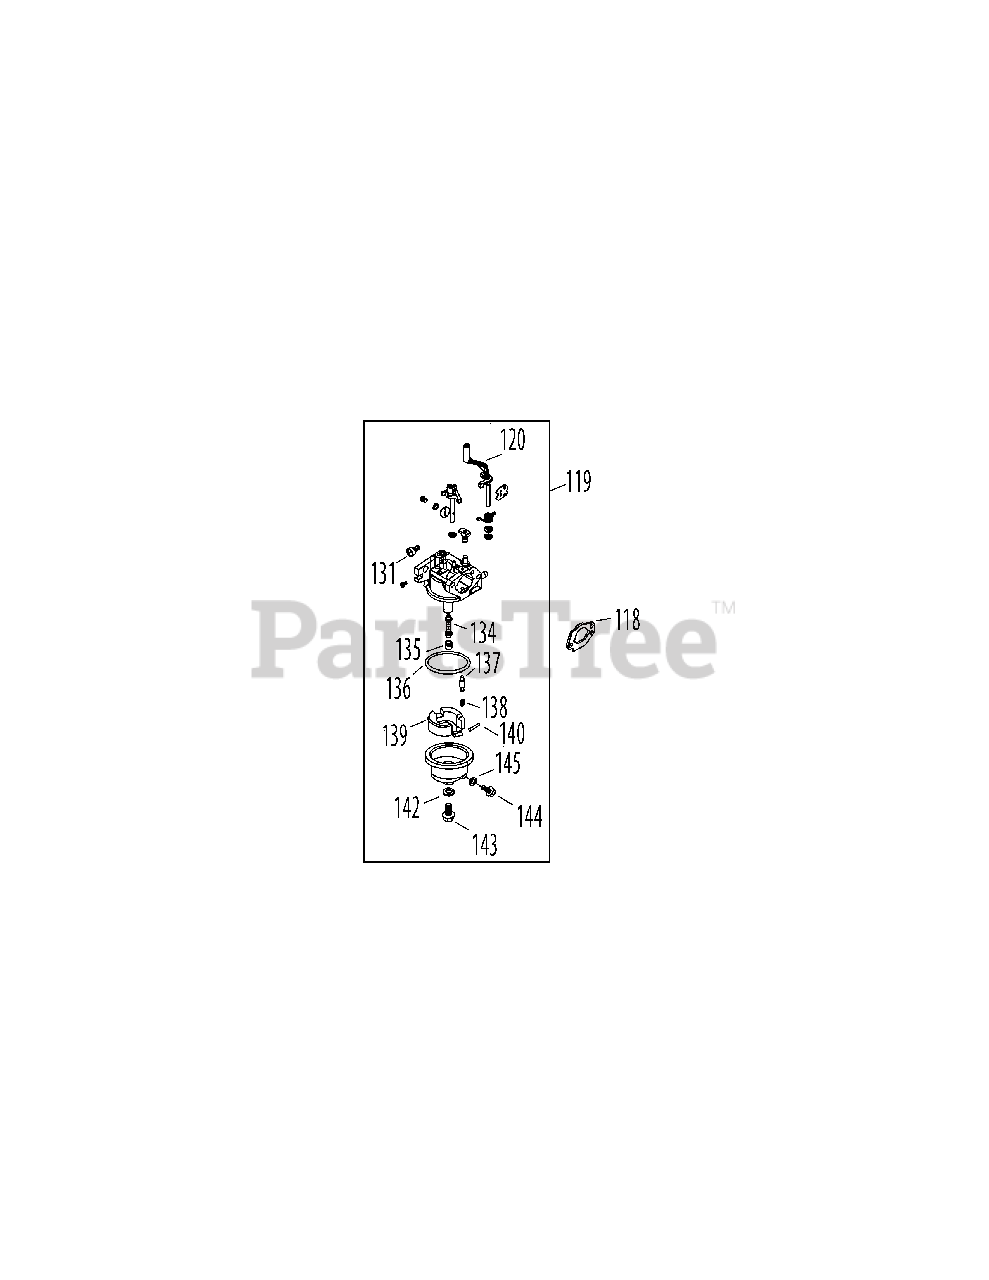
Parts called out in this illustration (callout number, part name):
118	Carburetor Gasket Plate
119	Carburetor Assembly
120	Choke & Throttle Shaft Dust Seals
131	Idle Speed Adjusting Screw
134	Main Nozzle / Emulsion Tube
135	Main Jet
136	Fuel Bowl O-Ring
137	Needle Valve (Float)
138	Needle Valve Spring
139	Float
140	Float Pin
142	Fuel Bowl Gasket
143	Fuel Bowl Mounting Bolt
144	Fuel Drain Plug
145	Fuel Drain Plug Gasket
